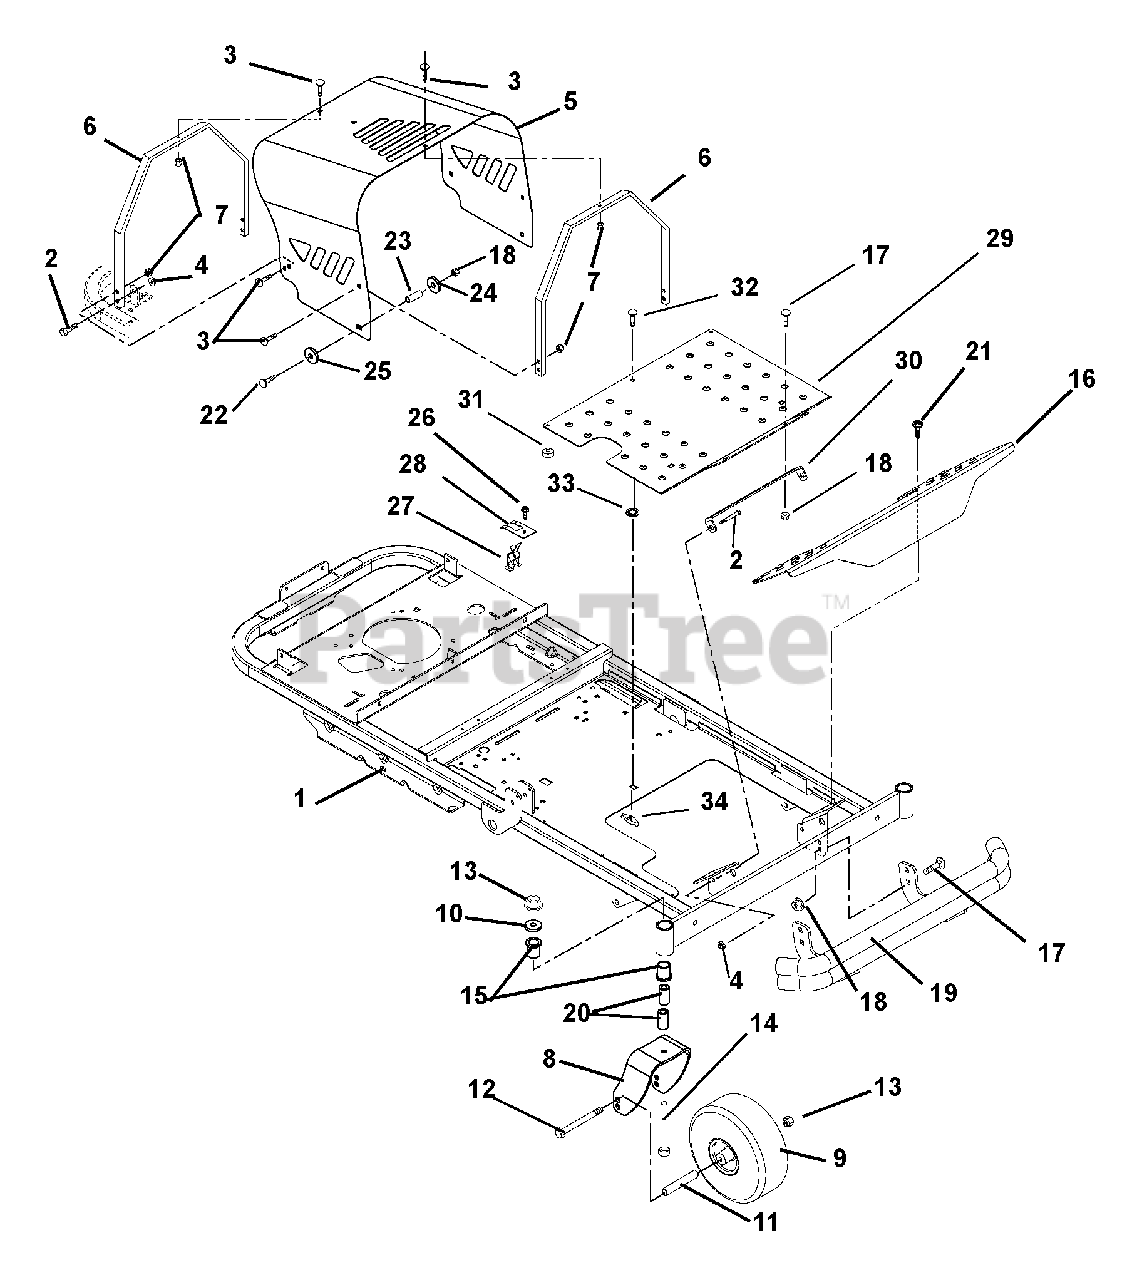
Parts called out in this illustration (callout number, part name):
1	WMT, FIXED AXLE FRAME
2	BOLT-SHLDR .375-16X.150
3	@BLT-RHDSSQNK .31-18X.62 G5YZ
4	@NUT-LK-TOP-FLG .38-16 YWZC
5	ENGINE HOOD, CE ZOOM
6	BRACE, HOOD
7	@NUT-LK-TOP-FLG .31-18 YWZC
8	FORK, CASTER- WELDED
9	ASSY-TIRE 4 X 11 - 4 PLY
10	WSHR-FL-STL.511X1.441X.125 YWZ
11	SPACER, ROLLED WHEEL
12	@BLT-HEX .50-13X6.50 GR5 YWZC
13	@NUT-LK-TOP-FLG .50-13 YWZC
14	@BLT-HEX .50-13X5.00 GR5 YWZC
15	BSHG-FLG 1.00X1.25X1.50X1.50EP
16	FOOTREST
17	@BLT-RDHDSQNK .38-16X1.00 G5YZ
18	@NUT-LK-NYL-FLG .38-16 YWZC
19	WMT, BUMPER
20	SPACER, CASTER .50X1.00X1.84
21	@SCR-TAP .31-18X.50 HWH TR YWZ
22	@BLT-RDHDSQNK .38-16X2.00 G2YZ
23	BSHG, SPCR .390X.625X1.25 PM
24	WSHR-FL-STL .375X1.125X.065YWZ
25	@WSHR-FL-STL.531X1.06X.095YWZC
26	@SCR-TAP .25-20X.50 HWH TR YWZ
27	HOOD CLIP
28	BRACKET, HOOD CLIP
29	PLATE, DECK ACCESS
30	BRACKET, DECK ACCESS
31	BUMPER GROMMET
32	@BLT-RDHDSQNK .31-18X1.00 G5YZ
33	NUT-PUSH .312
34	KNOB - WING .312-18 UNC
